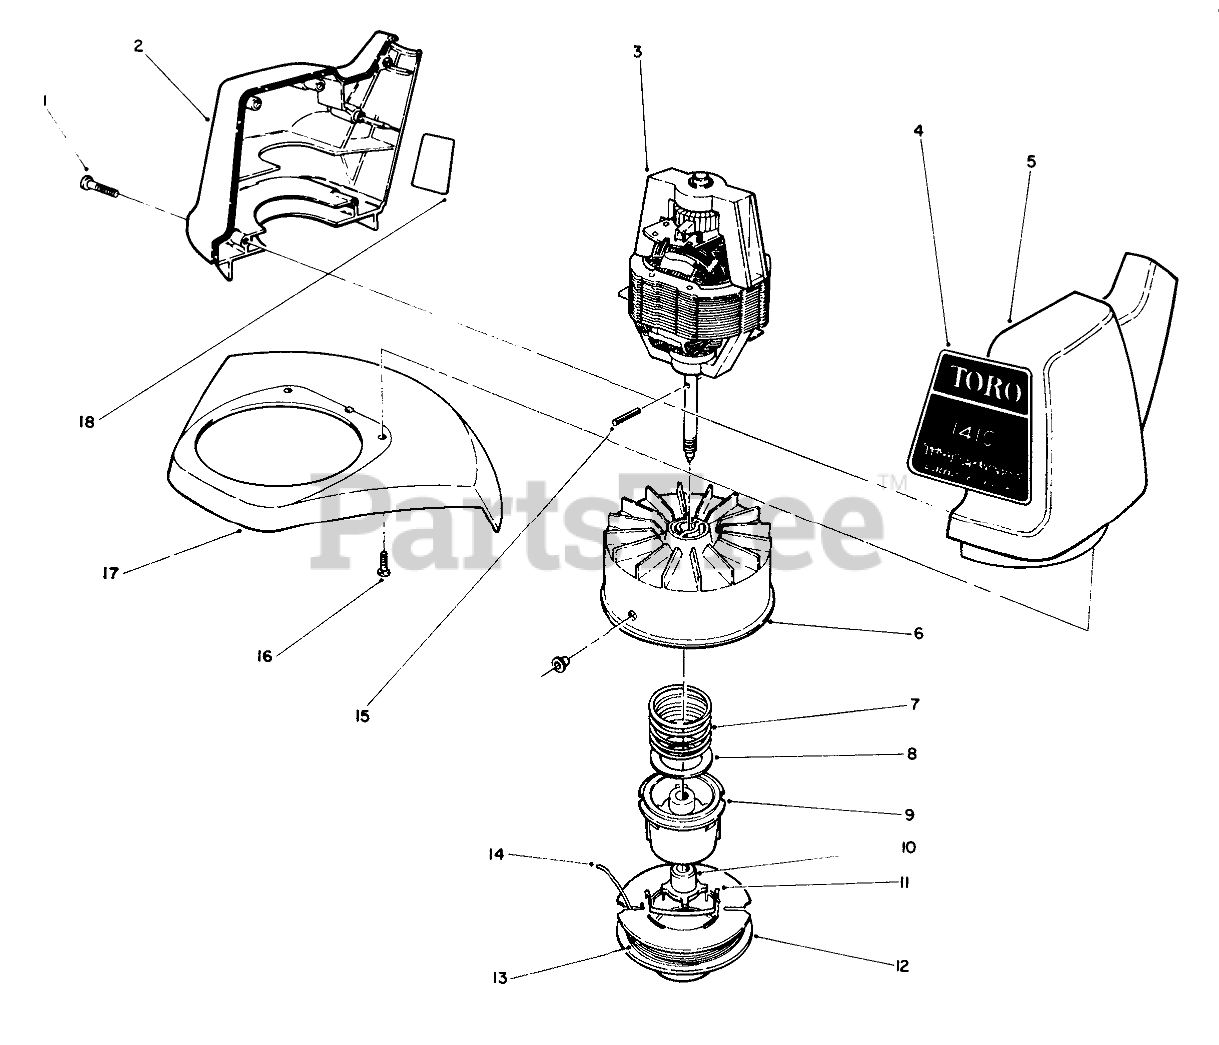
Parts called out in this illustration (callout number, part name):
1	SCREW-PPH
2	RH HOUSING, 1410
3	MOTOR, 1410 TRIMMER
4	DECAL, 1410
5	LH HOUSING, 1410
6	Drum & Eyelet Assembly
7	SPRING COMPRESSION
8	WASHER-FLAT
9	SPOOL CORE
10	DRIVER
11	SADDLE-SPOOL CAP
12	Empty Spool
13	Cutting Line (50 .065" Dia.)
14	LINE-FILIMENT
15	COIL PIN
16	SCREW-PPH
17	Shield Assembly
18	Decal
